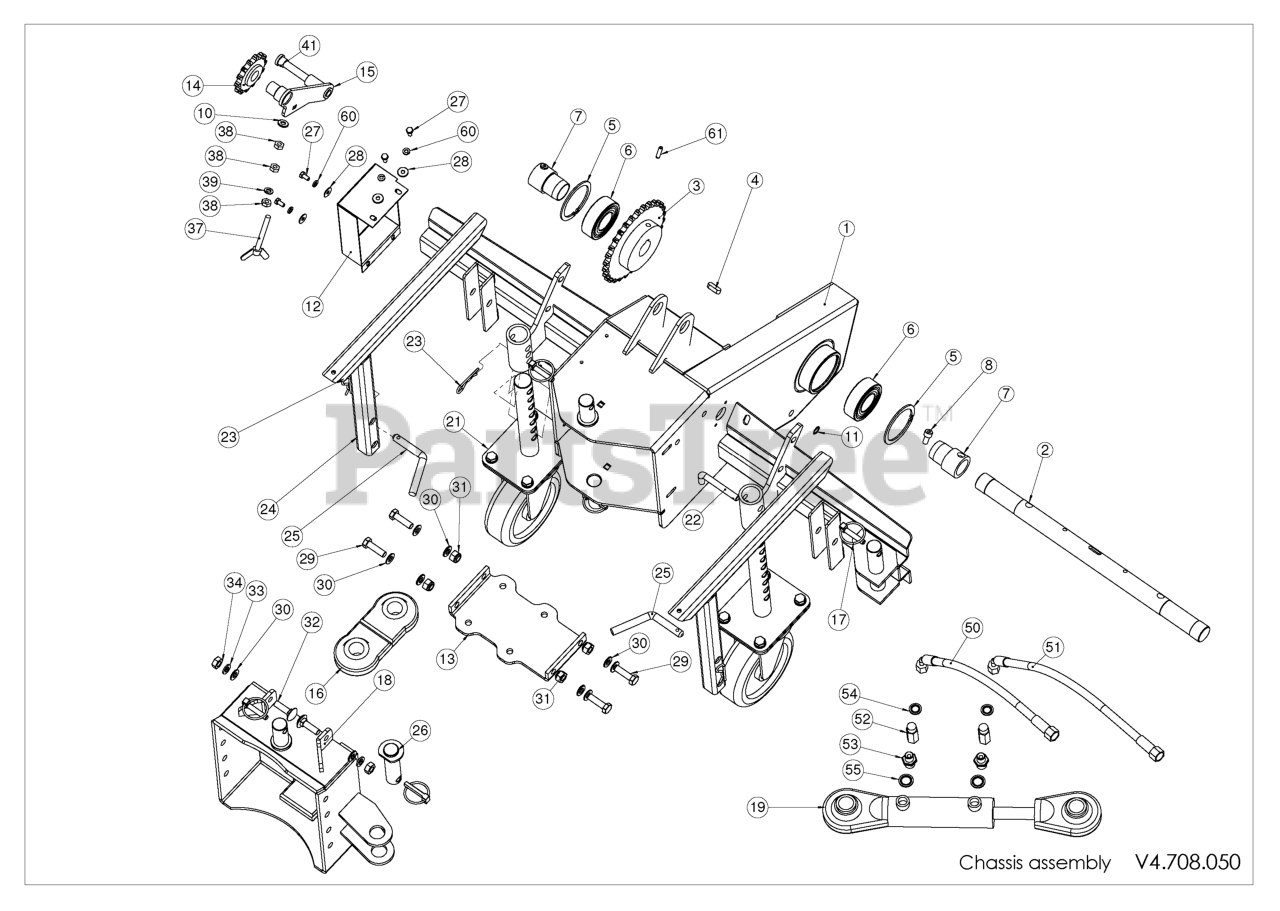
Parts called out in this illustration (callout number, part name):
10	WASHER BRB 8.4X17
11	RETAINING RING SGA 10
28	WASHER - 26X6.5X1.6
30	WASHER
31	NUT
34	NUT
38	NUT
